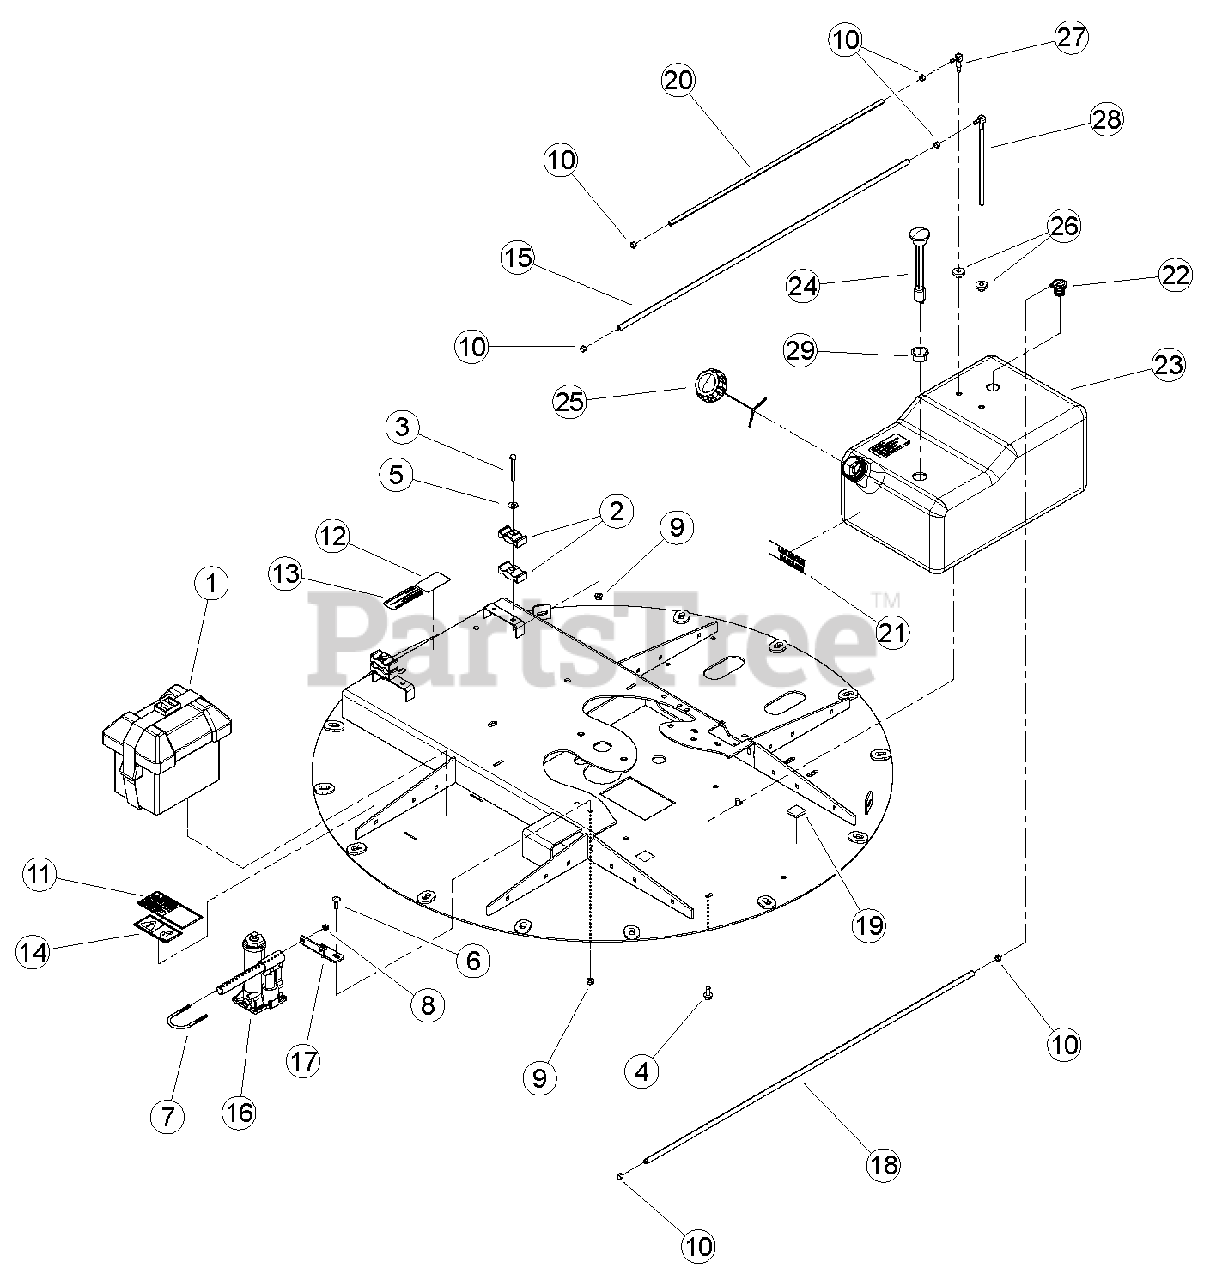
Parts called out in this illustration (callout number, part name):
1	BOX, SMALL BATTERY
2	CLAMP, PLASTIC HOSE
3	BOLT, 5/16 X 2-1/2 G5 HX CAP ZP
4	BOLT, 3/8 X 3/4 FLANGE NC
5	WASHER, 5/16" FLAT ZP
6	BOLT, 5/16 X 1" GR5 CRG ZP
7	U-BOLT, 1/4 X 1-1/2 PIPE
8	NUT, 1/4-20 NYLOCK-FLANGE
9	NUT, 5/16-18 NYLOCK-FLANGE
10	CLAMP, 15/32 SPRING
11	DECAL, HITCH TRANSPORT
12	DECAL, P215/70R15 LOAD RATING
13	DECAL, EPA EVAP
14	DECAL, LOCK
15	HOSE, 38" FUEL LINE
16	JACK, HYDRAULIC 2 TON
17	PLATE, JACK MOUNT
18	HOSE, 43 INCH FUEL LINE
19	PAD, FOAM FUEL TANK DAMPER
20	HOSE, 28 INCH FUEL LINE 1/4"
21	DECAL, UNLEADED GASOLINE
22	VALVE, ROLL OVER
23	TANK, ROTOMOLDED FUEL
24	GAUGE, FUEL LEVEL KELCH 100
25	CAP, NON-VENTED EPA/CARB APPROVED
26	GROMMET, TANK FITTING
27	FITTING, TANK VENT
28	FITTING, TANK FUEL PICK-UP TUBE
29	GROMMET, KELCH 100 GAUGE
